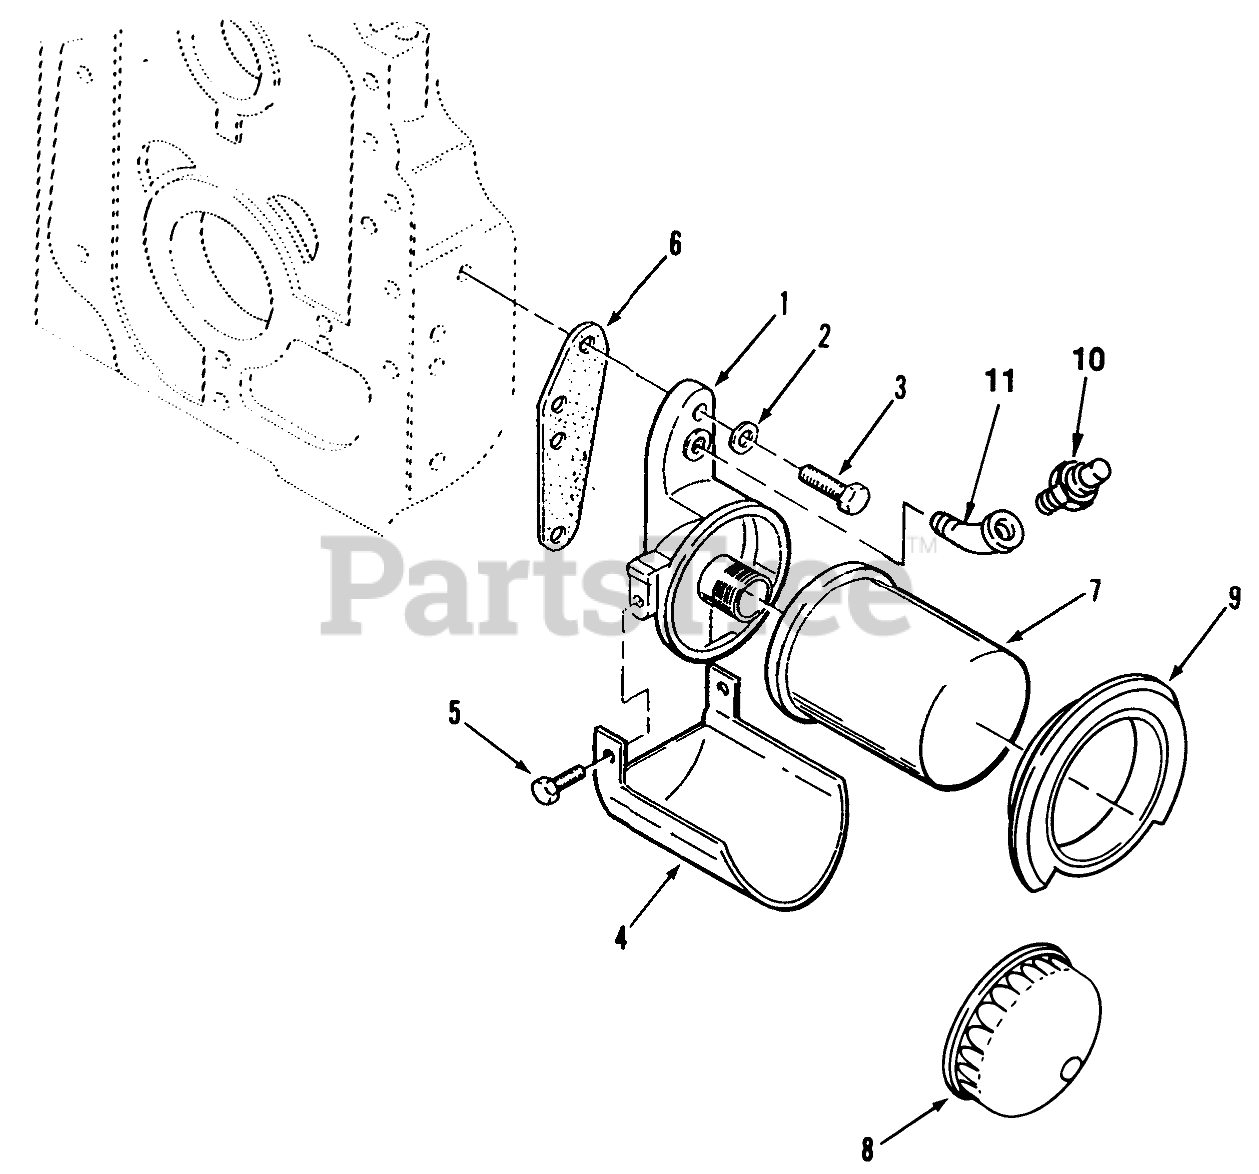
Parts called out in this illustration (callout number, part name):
1	Adapter
2	WASHER
3	HHCS 5/16-18 X 1
4	OIL-FILTER DRAIN
5	Bolt
6	Gasket
7	OIL FILTER
8	Wrench
9	Gasket
10	SWITCH
11	ELBOW-45 DEG
